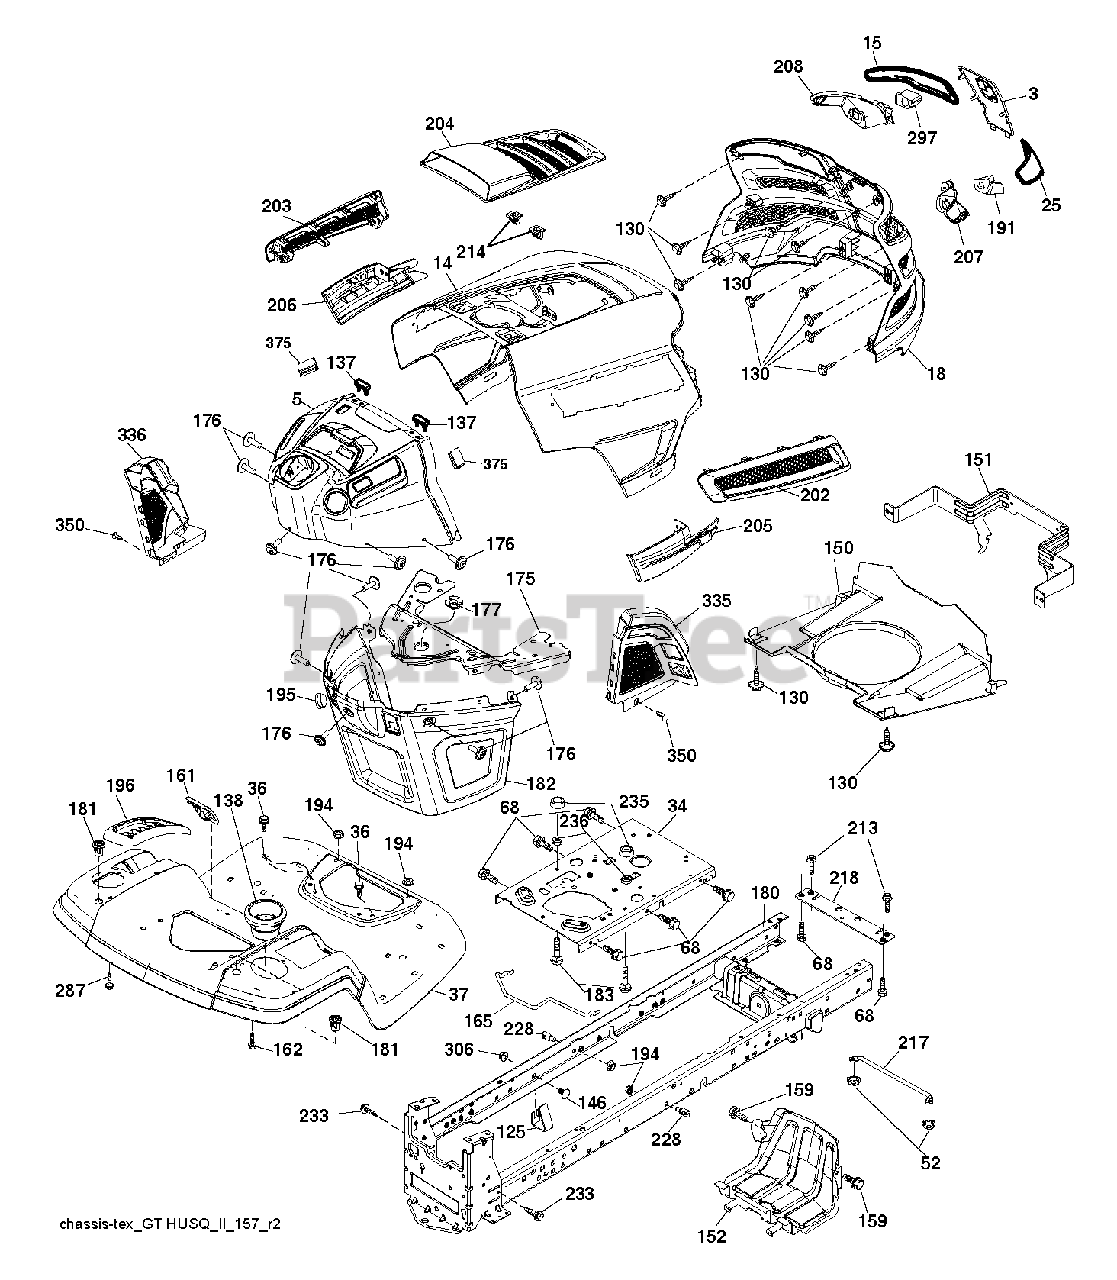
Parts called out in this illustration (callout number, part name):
3	BUMPER DASH
5	DASH.UPP.GT2.DUAL.RD.PT
14	HOOD.ASM.HUSQVARNA.GT.TEX.ORAN
15	LENS.HEADLIGHT.LH.GTII.2011
18	GRILLE SUBASM.GT.II.LOW.HDLGHT
25	LENS.HEADLIGHT.RH.GTII.2011
34	PLATE.ENGINE.WELDED.CHASSIS
36	SCREW 5/16"
37	FENDER.ERGO.LT.W/CPH.W/FW.ORNG
52	LOCKNUT
68	SCREW LT
125	CLIP.FUEL.LINE
130	SCREW.#10 X 0.750.BOS
137	BUMPER DASH
138	HOLDER.CUP.LT.GREY
146	BOLT.RDHD.SHT.SQNK.3/8-16X5/8
150	AIR.DUCT.GTV.BLACK
151	BRACKET.PIVOT.HOOD.GT.HUSQ.II
152	SHIELD.BROWNING.PNT.GT.V2
159	SCREW, 3/8-16X3/4
161	WINDOW.FUEL.LT.HUSQ.TEX.498
162	SCREW.HI-LO.CONSOLE
165	SUPPORT.TANK.REAR.W/TEX
175	PLATE.CROSSMEMBER.HUSQ
176	SCREW.#10-24X5/8.RN.QU
177	BUSHING STEERING
180	CHASSIS
181	BUSHING.MNT.FEND.CRGO.TEX.49
182	DASH.LOWER.COMMON.12V.ADAPTOR
183	BOLT.5/16-18X1-1/4 FULL THD
191	INSERT.REFLECTIVE.RH.HUSQ.GTII
194	NUT LOCK HEX FLANGE 5/16-18
195	PLUG.HOLE.DASH.LOWER.12V.BLK
196	DECKLFT.CONSOL FULL ASSM GREY
202	VENT.SIDE.RH.GT.HUSQ.II.
203	VENT.SIDE.LH.GT.HUSQ.II.498
204	VENT.TOP.HUSQ.GT2
205	SIDE.TRIM.RH.GT.HUSQ.II
206	SIDE.TRIM.LH.GT.HUSQ.II.GRAY
207	HEADLIGHT.CUP.BEZEL.HUS.GT2.RH
208	HEADLIGHT.CUP.BEZEL.HUS.GT2.LH
213	BOLT
214	CLIP.RETAINER.TINNER.
217	ROD.PIVOT.HOOD
218	X-PIECE.HOOD.STOP.NON/
228	STUD.FASTNER.W/ANTI-ROTATE
233	BOLT.SHOULDER
235	SPACER FENDER
236	NUT.CENTERLOCK.5/16-
287	SCREW 1/4X20
297	INSERT.REFLECTIVE.LH.HUSQ.GTII
306	NUT LOCK FLG 3/8-16 UNC
335	COVER.LOWER.DASH.RH.BLACK
336	COVER-LH.LOWER.DASH.GT2.BLACK
350	CLIP.X-MAS.TREE
375	BUMPER CLIP-ON. DASH 1"
